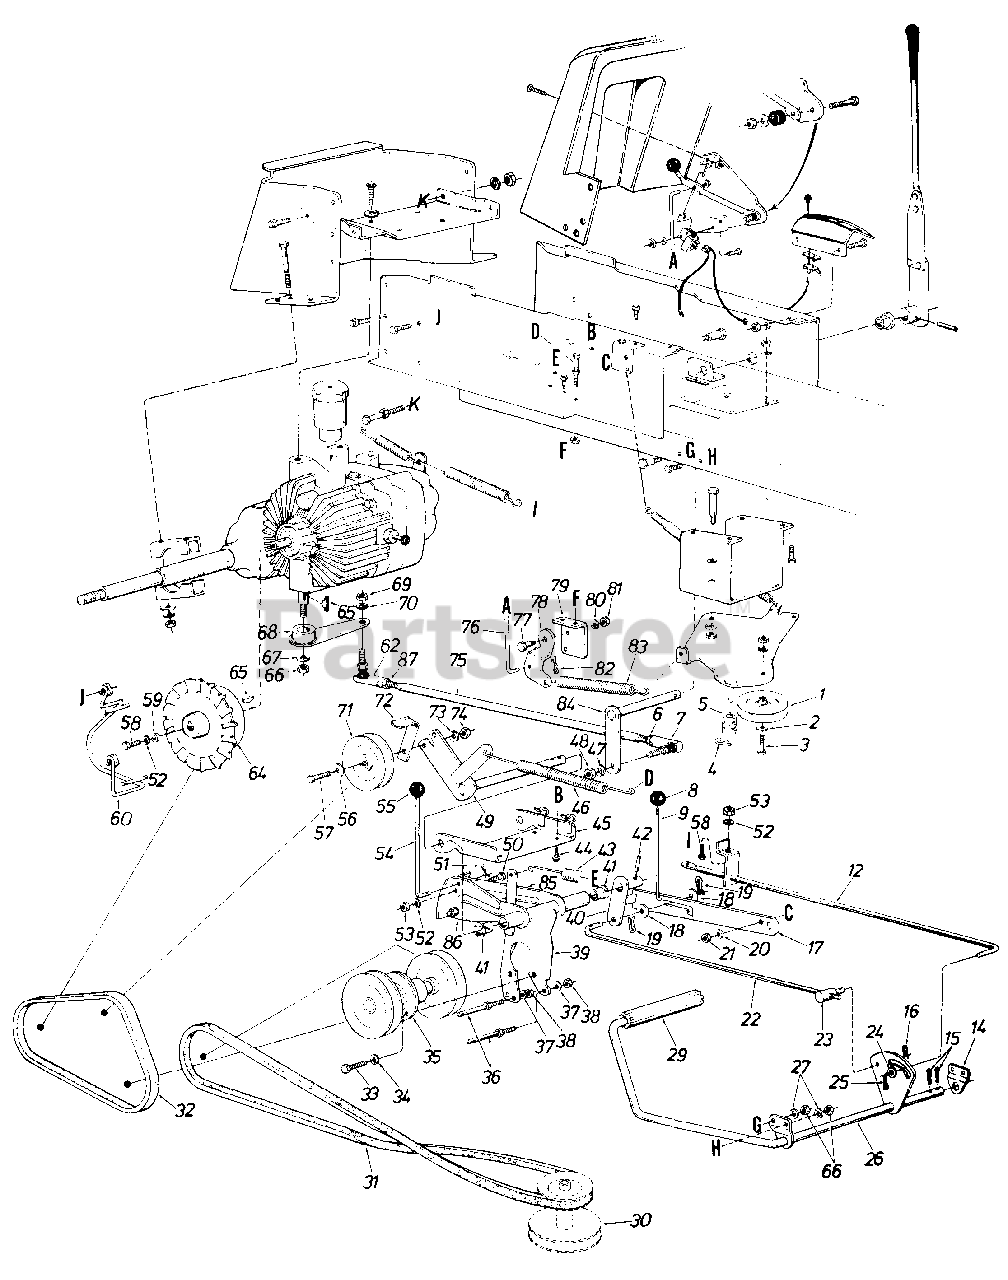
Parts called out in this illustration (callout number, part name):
1	4" Dia. "V"-Idler Pulley
2	Fl-Wash. 3/8" I.D.
3	Hex Bolt 3/8-16 x 1.25" Lg.*
4	Intern. Cotter Pin 5/16" Dia.
5	Spacer
6	Hex Jam L-Nut 3/8-24 Thd.
7	Ball Joint Ass'y. 3/8-24 Thd.
8	Ball Knob
9	Parking Brake Link
12	Brake Rod
14	Clutch Rod Brg. Brk't.
15	Cotter Pin 1/8" Dia. x 1.00" Lg.*
16	Hairpin Cotter 1/2" Dia.
17	Parking Brake Cam
18	Fl-Wash. .406 I.D. x 1.00" O.D. x .030
19	Hairpin Cotter 1/2" Dia.
20	Fl-Wash. 5/16" Scr.*
21	Hex Nut 5/16-18 Thd.*
22	Brake Cam Rod
23	Pivot Bushing
24	Fl-Wash. .401" I.D. x .749" O.D. x .057" Thk.
25	Cotter Pin 1/8" Dia. x 1.00" Lg.
26	Clutch Brake Pedal Ass'y.
27	L-Wash. 3/8" I.D.*
29	Foot Pad
30	Two-Step Engine Pulley 4.75" and 5.56"
31	"V"-Belt 1/2" x 59" Lg.
32	"V"-Belt 1/2" x 37" Lg.
33	Hex Sems Bolt 5/16-18 x .75" Lg.*
34	L-Wash. 5/16" I.D.*
35	Jack Shaft Ass'y.
36	Stud 3/8-16 x 3.62" Lg.
37	L-Wash. 3/8" I.D.*
38	Hex Nut 3/8-16 Thd.*
39	Jack Shaft Mtg. Brk't. Ass'y.
40	Clutch Idler Horn Ass'y.
41	Nyliner 5/8" I.D. x .88" Lg.
42	Spring Pin Spiral 1/4" Dia. x 1.5" Lg.
43	Ext. Spring
44	Hex Wash. Hd. Self-Tap Scr. 1/4-20 x .50" Lg.
45	Idler Mtg. Brk't.
46	Ext. Spring
47	L-Wash. 3/8" I.D.
48	Hex Nut 3/8-24 Thd.
49	Clutch Brk't. Ass'y.
50	Hex Bolt 1/4-20 x .50" Lg.
51	Internal Cotter Pin 5/16" Dia. Rod
52	L-Wash. 1/4" I.D.
53	Hex Nut 1/4-20 Thd.
54	Relief Valve Lockout Rod
55	Ball Knob
56	Fl-Wash. 3/8" I.D.
57	Hex Bolt 3/8-16 x 1.25" Lg.
58	Hex Bolt 1/4-20 x .62" Lg.*
59	Fl-Washer
60	Belt Guard Ass'y.
62	Ball Joint Ass'y. 3/8-24 L.H. Thd.
64	Transaxle Pulley w/Fan
65	Hi-Pro Key 118" x 1/2" Dia.
66	Hex Nut 3/8-16 Thd.
67	L-Wash. 3/8 I.D.
68	Pintle Arm Ass'y.
69	Hex Nut 3/8-24 Thd.*
70	L-Wash. 3/8 I.D.
71	4" "V"-Idler Pulley
74	Hex Nut 3/8-16 Thd.
75	Speed Control Rod
76	Deck Control Rod
77	Shld. Scr. .437" Dia. x .162" Lg. (5/16-18)
78	Deck Control Pivot Brk't.
79	Parking Brake Cam Mtg. Brk't.
80	L-Wash. 5/16" I.D.
81	Hex Nut 5/16-18 Thd.*
82	Internal Cotter Pin 5/16" Roc
83	Extension Spring
84	Speed Control Shaft Ass'y.
85	Relief Valve Cam L.H.
86	Relief Valve Cam R.H.
87	Hex Jam L-Nut 3/8-24 L.H. Thd.
